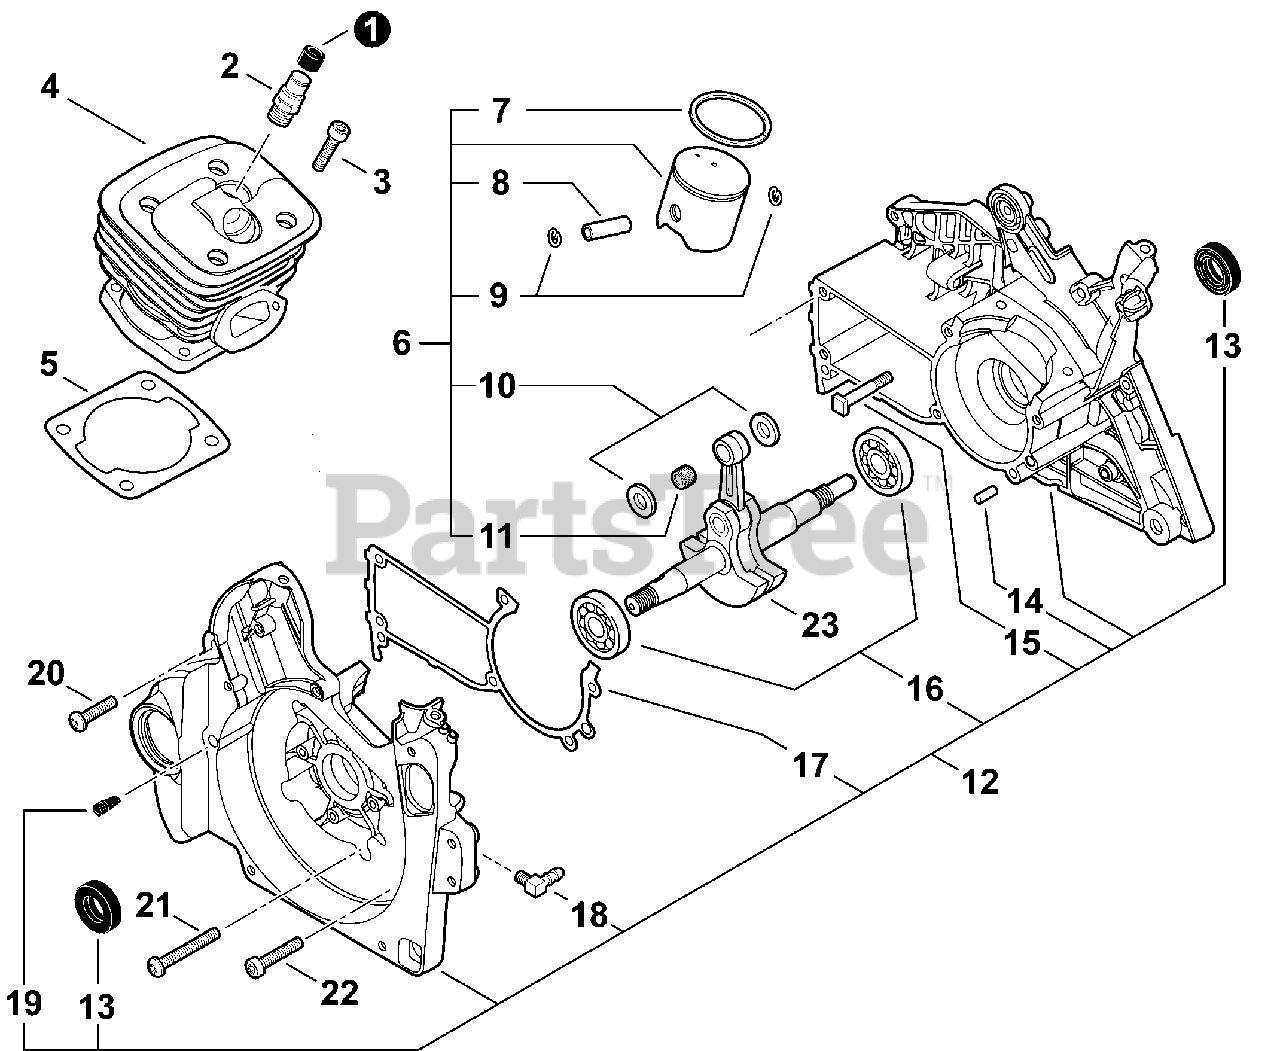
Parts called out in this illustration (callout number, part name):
1	COVER, DUST
2	VALVE ASSY, DECOMPRESSION
3	BOLT, TORX 5×25
4	CYLINDER
5	GASKET, CYLINDER
6	PISTON KIT
7	RING, PISTON
8	PIN, PISTON
9	RING, SNAP Ø11
10	WASHER, THRUST
11	BEARING, NEEDLE 11
12	CRANKCASE KIT
13	SEAL, OIL 15
14	PIN, LOCATING 5×10
15	BOLT, STUD M8×1.25×34.5
16	BEARING, BALL 6202
17	GASKET, CRANKCASE
18	CONNECTOR, PIPE
19	VENT ASSY
20	BOLT, TORX 5×20
21	BOLT, TORX 5×35
22	BOLT, TORX 5×25
23	CRANKSHAFT ASSY
